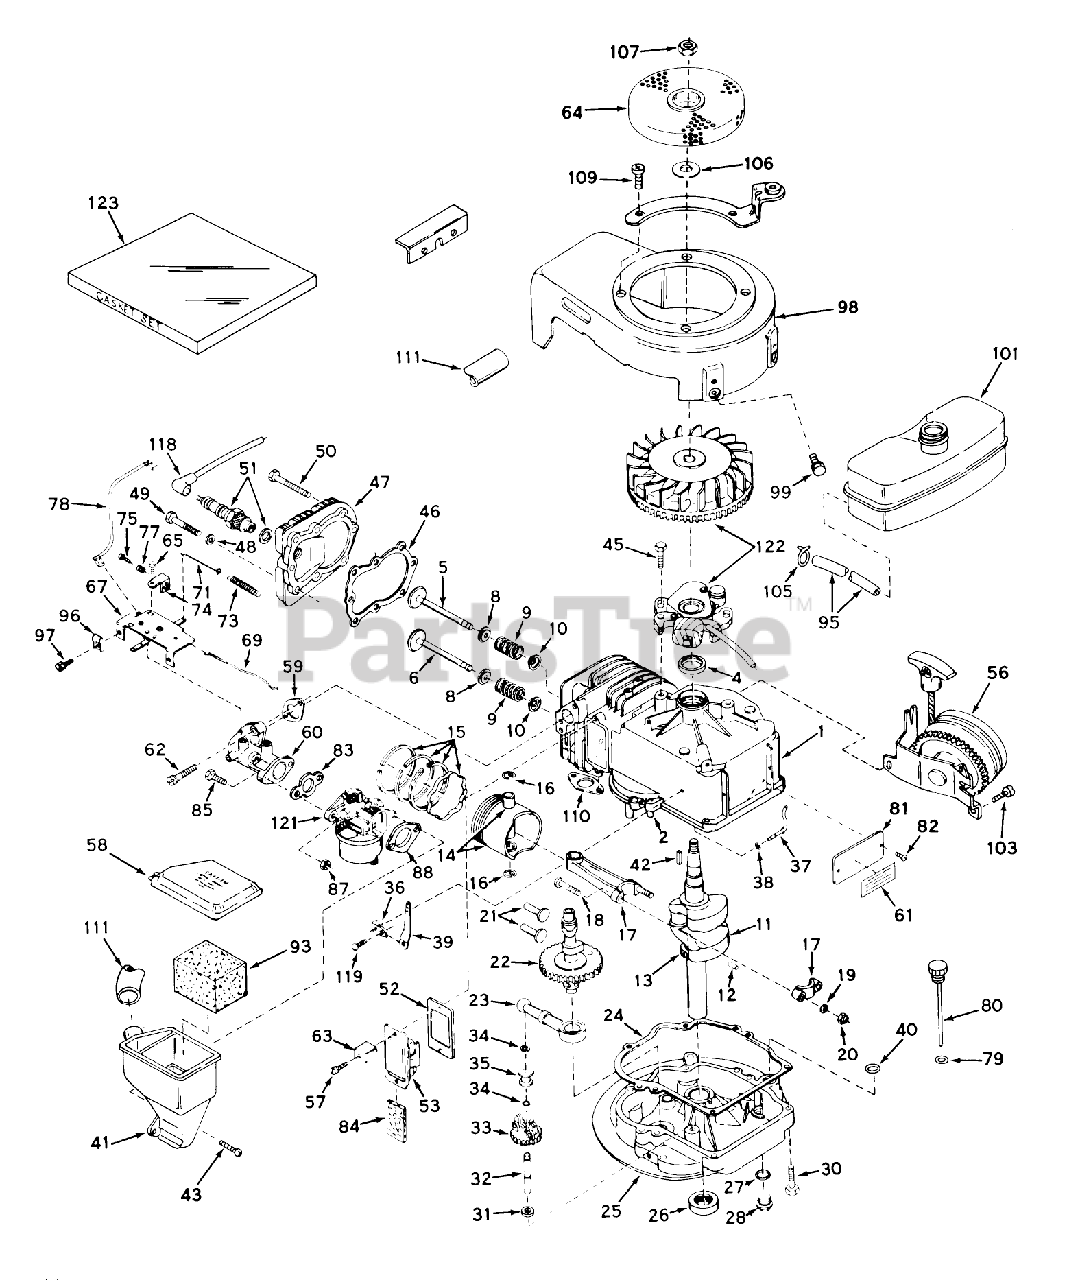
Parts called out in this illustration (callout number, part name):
1	Cylinder Assy. (Incl. Ref. 2 4)
2	Pin-Dowel
4	OIL SEAL
5	Valve, Intake (Incl. Ref. #38, 39 40) (Std.)
5	Valve, Intake(1/32"overs.)(Incl. Ref. 8, 9 10)
6	Valve, Exhaust (Standard)(Incl. Ref. 8, 9 10)
6	Valve, Exhaust (1/32" Overs.(Incl. Ref. 8, 9 10)
8	Cap-Upper Valve Spring
9	Spring-Valve
10	Cap-Valve, Spring
11	Crankshaft Assy. (Incl. Ref. 12 13)(Model LAV35-40455H)
11	Crankshaft Assy. (Incl. Ref. 12 13)
12	Pin, Groove
13	Gear, Crankshaft
14	Piston Pin Assy. (Incl. 2 of No. 16)(Standard)
14	Piston Pin Assy. (Incl. 2 of No. 16)(.010 oversize)
14	53020 ADN. TO 28594
15	Piston Ring Set Std.
15	Piston Ring Set .010 O.S.
15	Piston Ring Set .020 O.S.
16	Ring-Retaining, Piston Pin
17	Rod Assy., Connecting (Incl. Ref. #17)
18	Bolt, Connecting
19	Washer
20	LOCKNUT
21	Lifter-Valve
22	Camshaft
23	Oil Pump ASM
24	Gasket, Mounting
25	Flange Assy., Mounting (Incl. Ref. 26, 27, 28 32)
26	Seal Oil
27	Gasket-Oil Drain
28	Plug Oil Drain
30	Screw (1/4-20 x 1-1/4)
31	Washer-Flat
32	Shaft-Governor
33	Governor Gear ASM
34	Ring-Retaining
35	Spool-Governor
36	Clamp-Lever, Governor
37	Rod, Governor (Incl. No. 36)
38	Washer-Flat
39	Governor Lever
40	O-Ring
41	Body, Air Cleaner
42	Key Flywheel
43	Screw, Fil. Hd. Sems
45	Screw
46	Gasket-Cylinder Head
47	CYLINDER HEAD
48	Washer
49	Screw
50	Screw Hex Hd. Cap
51	SPARK PLUG
52	Gasket, Breather
53	Breather Assembly (Incl. Nos. 52 84)
56	Starter, Side Mount
57	Screw
58	Cover, Air Cleaner
59	Gasket, Intake
60	Pipe, Intake
61	480B GIL SNWTHWR O/
62	Screw, Fil. Hd. Sems
63	Retainer Clip
64	Screen, Flywheel
65	Screw (10-24 x 9/16)
67	Control Assy., Speed
69	Link Governor
71	Link-Governor
73	Spring, Governor
74	Brachet, Control
75	Screw, Hex Hd.
77	Spring
78	Wire, Ground
79	O-Ring
80	Dipstick, Oil
81	IDENTIFICATION PLATE
82	Stud
83	Gasket
84	Element-Breather
87	Nut and Lock Washer (1/4-28)
88	Gasket-Air Cleaner
93	Element, Air Cleaner
95	Line-Fuel (8.62)
96	Conduit
97	Screw (10-32 x 3/8)
98	Housing, Blower
99	Screw (1/4-20x19/32)
101	Tank, Fuel
103	Screw
105	Clamp-Line, Fuel
106	Washer
107	Hex Nut
109	Screw
110	Gasket Exhaust
111	Tube, Air Cleaner
118	Cover-Spark Plug
119	Screw
121	Carburetor
122	Magneto
123	Gasket Set (Incl. Items Marked *)
